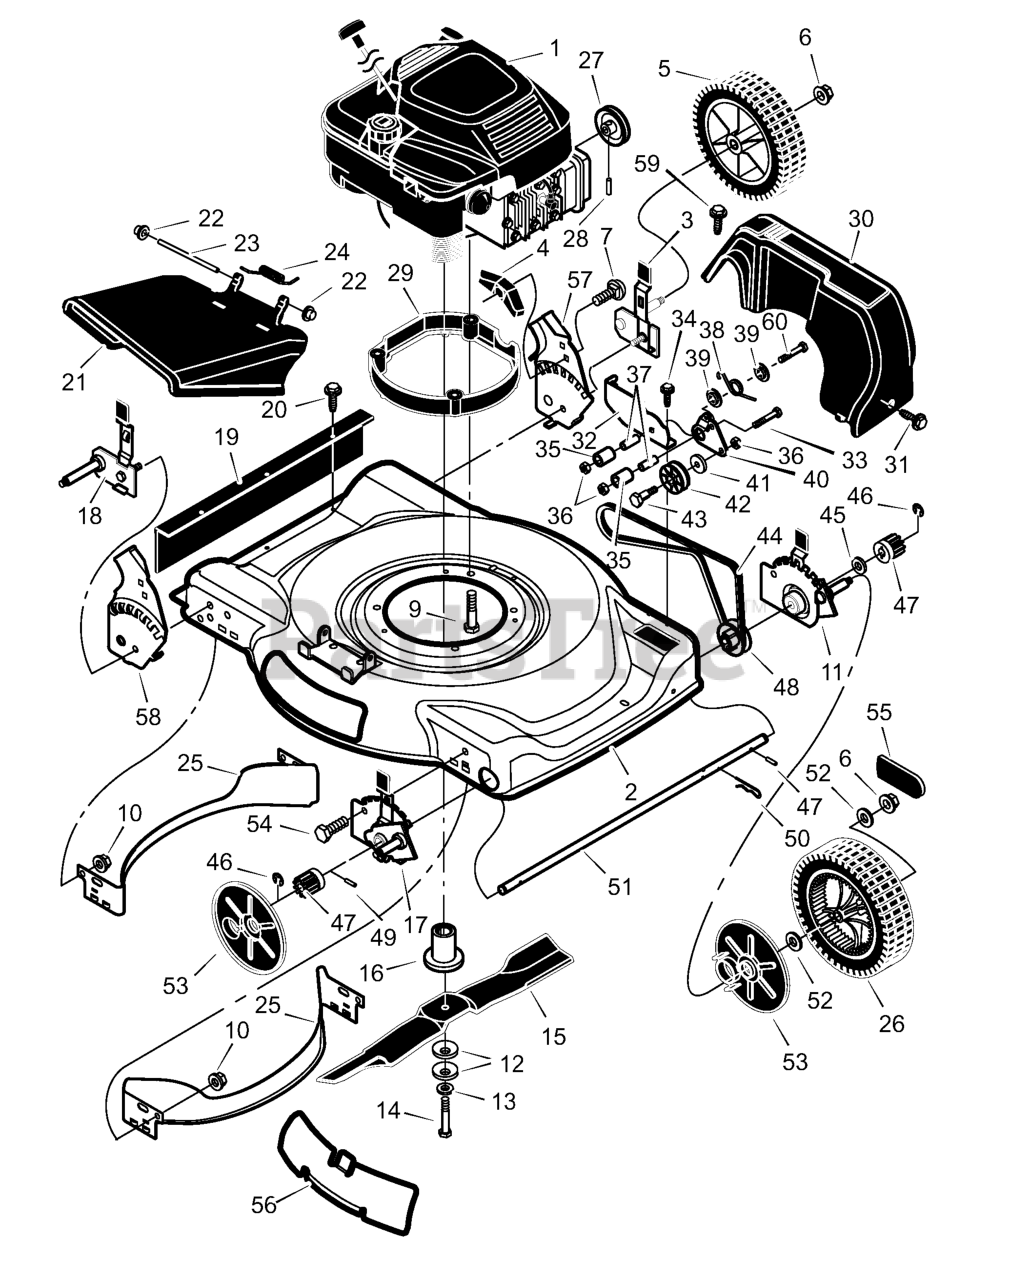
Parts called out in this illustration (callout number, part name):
1	Engine *
2	Housing
3	Height Adjuster, Left Rear
5	Wheel and Tire, Rear
6	Locknut, Flange
7	Bolt, Carriage
9	Bolt, Engine
10	Nut
11	Height Adjuster, Left Front
12	Washer, Belleville
14	Bolt, Hex
15	Blade, Mulcher
16	Adapter, Blade
17	Height, Adjuster, Right Frt.
18	Height, Adjuster, Right Rr.
19	Guard, Rear
21	Deflector, Chute
22	Push-On Cap
23	Pin, Pivot
26	Wheel and Tire, Drive
28	Pin, Spring
29	Base, Engine
30	Cover, Belt (Black)
32	Bracket, Idler Support
35	Idler, Backside
36	Locknut
37	Bearing
40	Arm, Pivot
42	Pulley, Idler
43	Bolt, Shoulder
44	Belt, Briggs & Stratton
46	Ring, Retainer
47	Gear, Pinion
49	Pin, Drive
50	Pin, Hair
52	Washer
53	Cover, Dust
54	Bolt
55	Hub Cap
56	Plate, Mulcher
57	Bracket, Left Handle
58	Bracket, Right Handle
